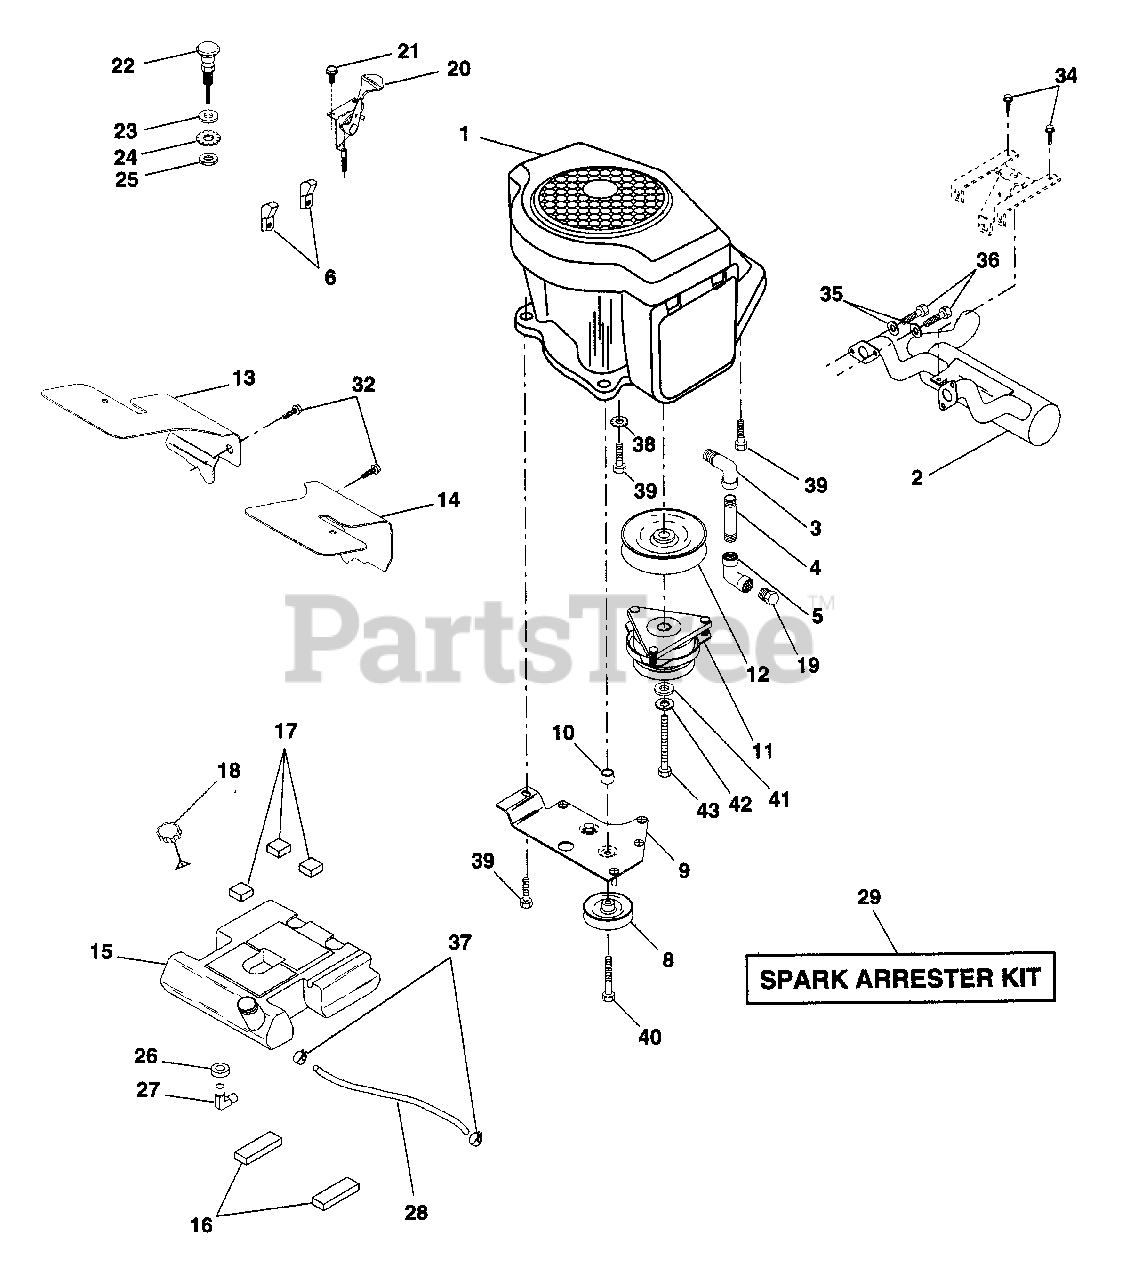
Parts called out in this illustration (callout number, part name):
2	Muffler Asm Kohler VGT
3	Elbow Street 3/8 NPT
4	Nipple Pipe 3/8NPT X 3 - 1/2
5	Elbow STD 90 Degree 3/8 - 18 NPT
6	Clamp Tube Double Engine
8	Pulley V-Idler
9	Stop Keeper Asm VGT
11	Clutch Electric
12	Pulley Engine VGT Elect Clutch
13	Baffle Air LH Koh VGT
14	Baffle Air RH Koh VGT
15	Tank Fuel W/Sym Vented
16	Pad Spacer
17	Pad Spacer
18	Cap Asm Fuel W/Sym Vented
19	Plug Oil Drain
20	Control Throttle
21	Screw Hex Thd Cut 1/4 - 20 X 5/8
22	Control Choke
23	Washer 13/32 X 13/16 x 16 Ga
24	Washer Ext Tooth 3/8
25	Nut Fin Hex 3/8 - 24 UNF
26	Bushing
27	Stem Tank Fuel
28	Fuel Line
29	Spark Arrester Kit
32	Screw Thdrol 5/16 - 18 X 1/2
34	Screw Thd Cut 1.4 - 20 x 1/2
35	Washer Lock 5/16
36	Screw Hex 5/16 - 16 UNC X 3/4
37	Clamp Hose
38	Lockwasher Ext Tooth 3/8
39	Screw Thdrol 3/8 - 16 X 1 - 1/2 TT
40	Screw Thdrol 3/8 - 16 X 3 - 1/4
41	Washer 1-1/2 OD X 15/32 ID X .250
42	Washer Lock 7/16
43	Bolt Hex 7/16-20 X 4-1/4 Ga 5
